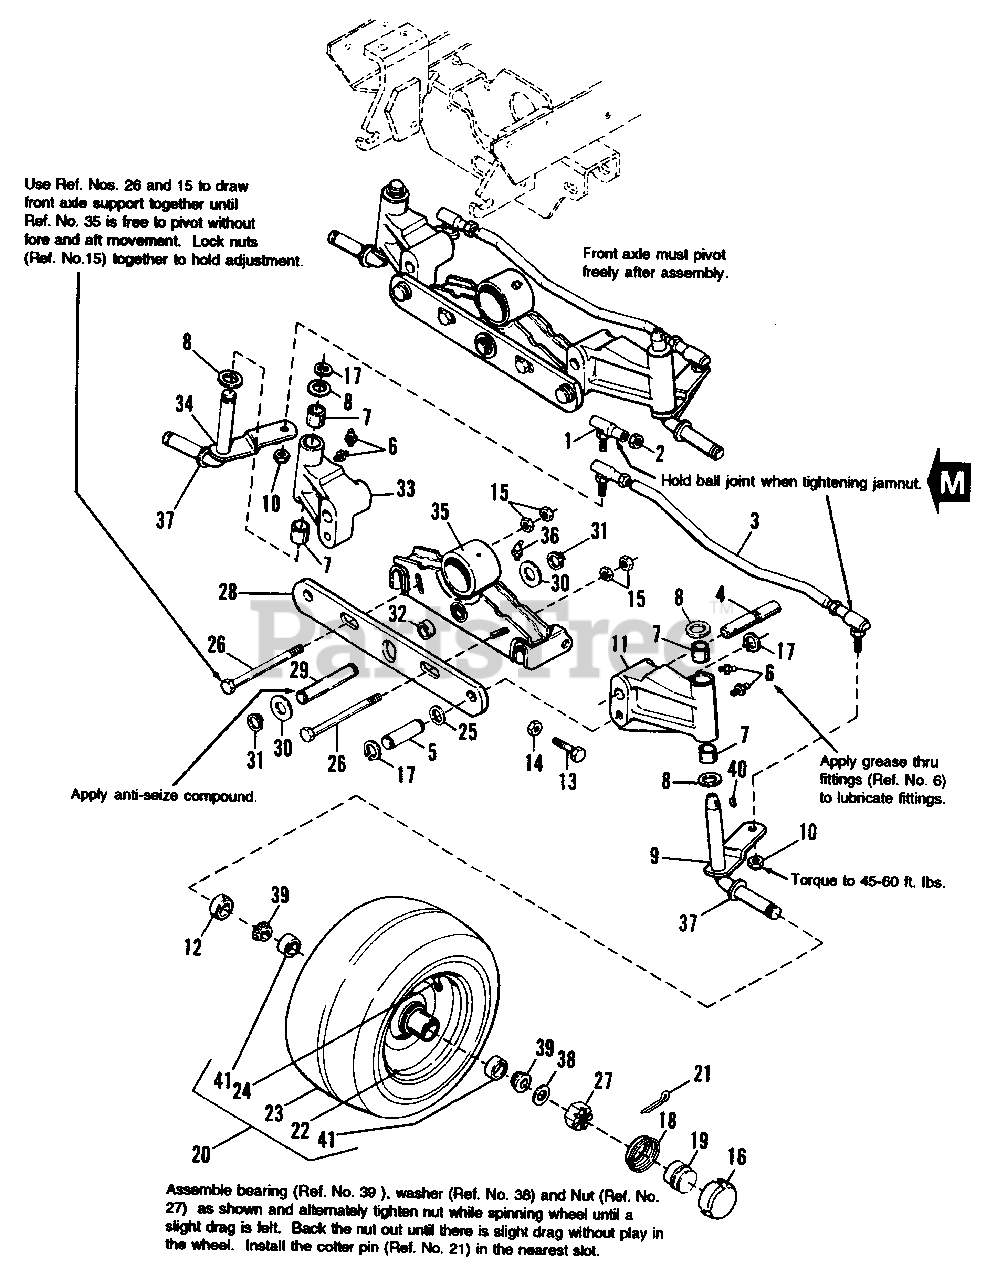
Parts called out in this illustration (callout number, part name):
1	BALL JOINT ASSY.
2	NUT, Hex, Jan, 1/2-20
3	TIE ROD ASSY. (Incl. Ref. No. 1 & 2)
4	PIN, Axle Pivot
5	PIN, Axle Pivot
6	FITTING, Lube, 1/4-28
7	BUSHING, Spindle
8	WASHER, 1-1/32 x 1-5/8 x 1/16
9	SPINDLE ASSY. L.H., (Includes Ref. No. 37)
10	NUT, Hex, Centerlock, 1/2-20
11	AXLE Pivot ASSY., L H. Qty 2 of Ref. Nos. 6 & 7)
13	CAPSCREW, Hex Hd., 5/16-18 x 1 3/4, Gr. 5
14	NUT, Hex, Centerlock, 5/16-18
15	Nut, Hex, 3/8-16
16	CAP, Hub, Cover
17	RING, Retainer
18	RETAINER, Hub Cap
20	FRONT WHEEL & TIRE ASSY., 16 x 6.50-8 (Beige)(Incl. Ref. Nos. 22. 23, 24 & 41 )
20	FRONT WHEEL & TIRE ASSY., 16 x 6.50-8 (Silver)(Incl. Ref. Nos. 22. 23, 24 & 41 )
21	PIN, Cotter, 1/8 x 1 3/4
22	WHEEL ASSY., w/ Bearings (Incl. Ref. No. 39)
22	WHEEL ASSY., w/ Bearings (Incl. Ref. No. 39)(Silver)
23	TlRE, 16 x 6.50-8
24	VALVE STEM & CAP
25	WASHER, 1 1/32 x 1 3/4 x 7 Ga.
26	CAPSCREW, Hex Hd., 3/8-16 x 4
27	NUT, Hex, Slotted Hd., 3/4-16
30	WASHER, 3/4 I.D.
31	RING, Retaining, 3/4 I.D.
33	AXLE PIVOT ASSY., R.H. (Incl. Qty 2 of Ref. Nos. 6 & 7)
34	SPINDLE ASSY., R.H. (Includes Ref. No. 37)
35	HITCH SUPPORT ASSY.
36	FITTING, Lube, 45ø, 1/4", Drive Type
37	COLLAR, Seal, Spindle, Assy.
39	BEARING, Cone
40	KEY, Hi-Pro, 1/4 x 3/4
41	BEARING, Cup, Wheels
